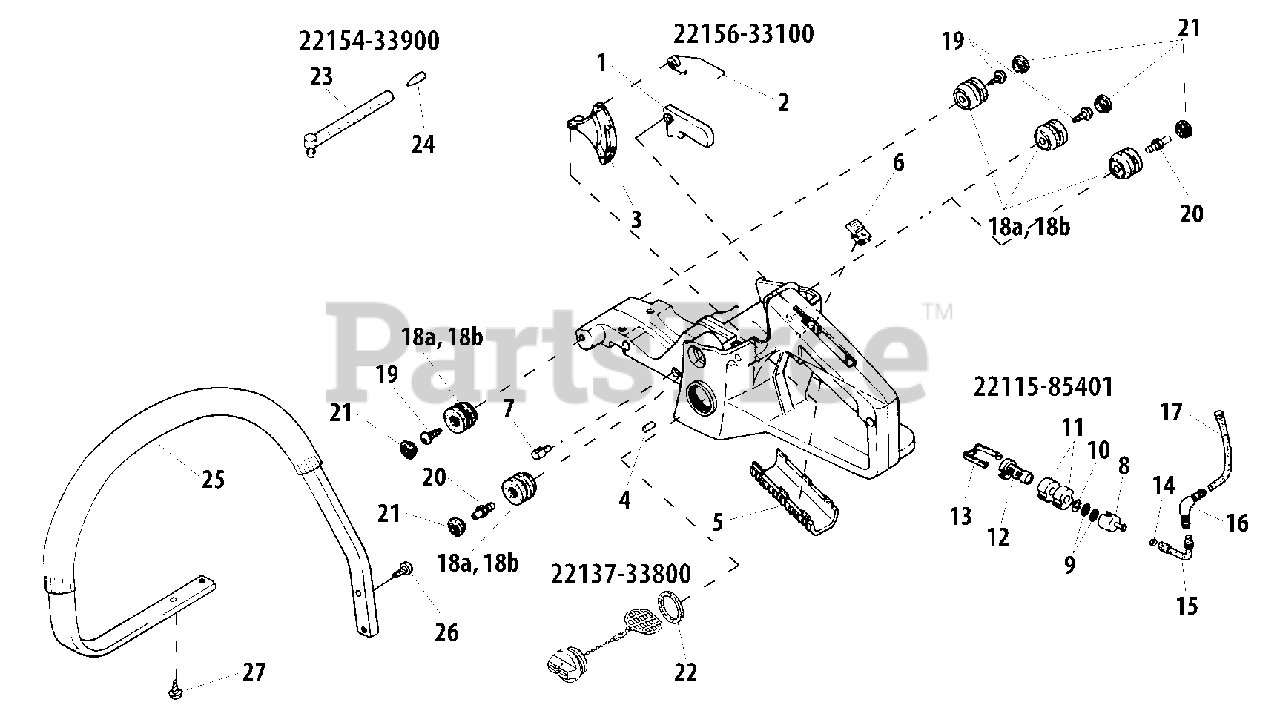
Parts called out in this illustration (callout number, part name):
1	LOCKOUT, THROTTLE
2	SPRING, LEVER
3	TRIGGER, THROTTLE
4	PIN 4×25
5	GRIP
6	STOPPER, SLIDE
7	SUPPORT
8	WEIGHT, FUEL LINE
9	SCREEN, FILTER
10	RING, RETAINING
11	FILTER, FUEL
12	BODY, FUEL FILTER
13	CLIP, FILTER
14	CLIP Ø6
15	PIPE, FUEL
16	CONNECTOR
17	PIPE, FUEL
19	BOLT M5
20	BOLT M5
21	CAP, CUSHION
22	GASKET, CAP
23	PIPE, FUEL VENT
24	VENT ASSY
25	HANDLE, FRONT
26	BOLT 5×21
27	BOLT 5×17
22115-85401	FILTER, FUEL
22137-33800	CAP ASSY, FUEL
22154-33900	VENT ASSY
22156-33100	REAR HANDLE ASSY
